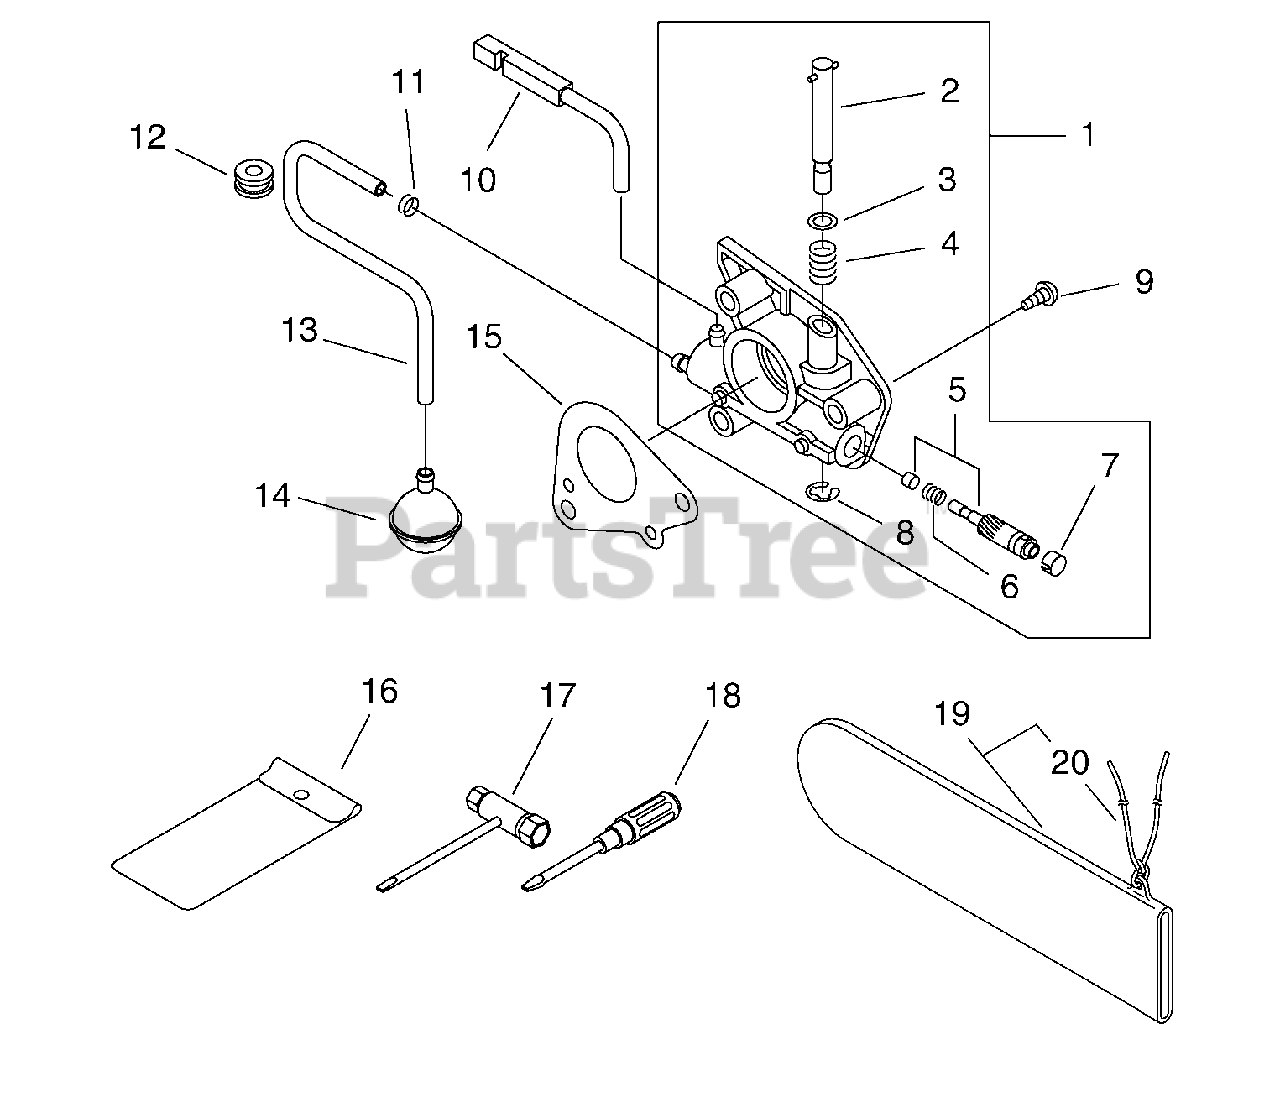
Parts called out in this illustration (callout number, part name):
1	AUTO-OILER ASSY
2	SCREW, ADJUSTER
5	PLUNGER ASSY
7	CAP, OIL PUMP
9	SCREW 4×16
10	PIPE, OIL OUTLET
11	CLIP 6.5 MM
13	PIPE, OIL
14	FILTER, OIL
15	PLATE, SEAL
16	BAG, TOOL
17	T-WRENCH 13×19 L= 180
18	SCREWDRIVER, SLOTTED
19	SCABBARD
20	ROPE 5×900
